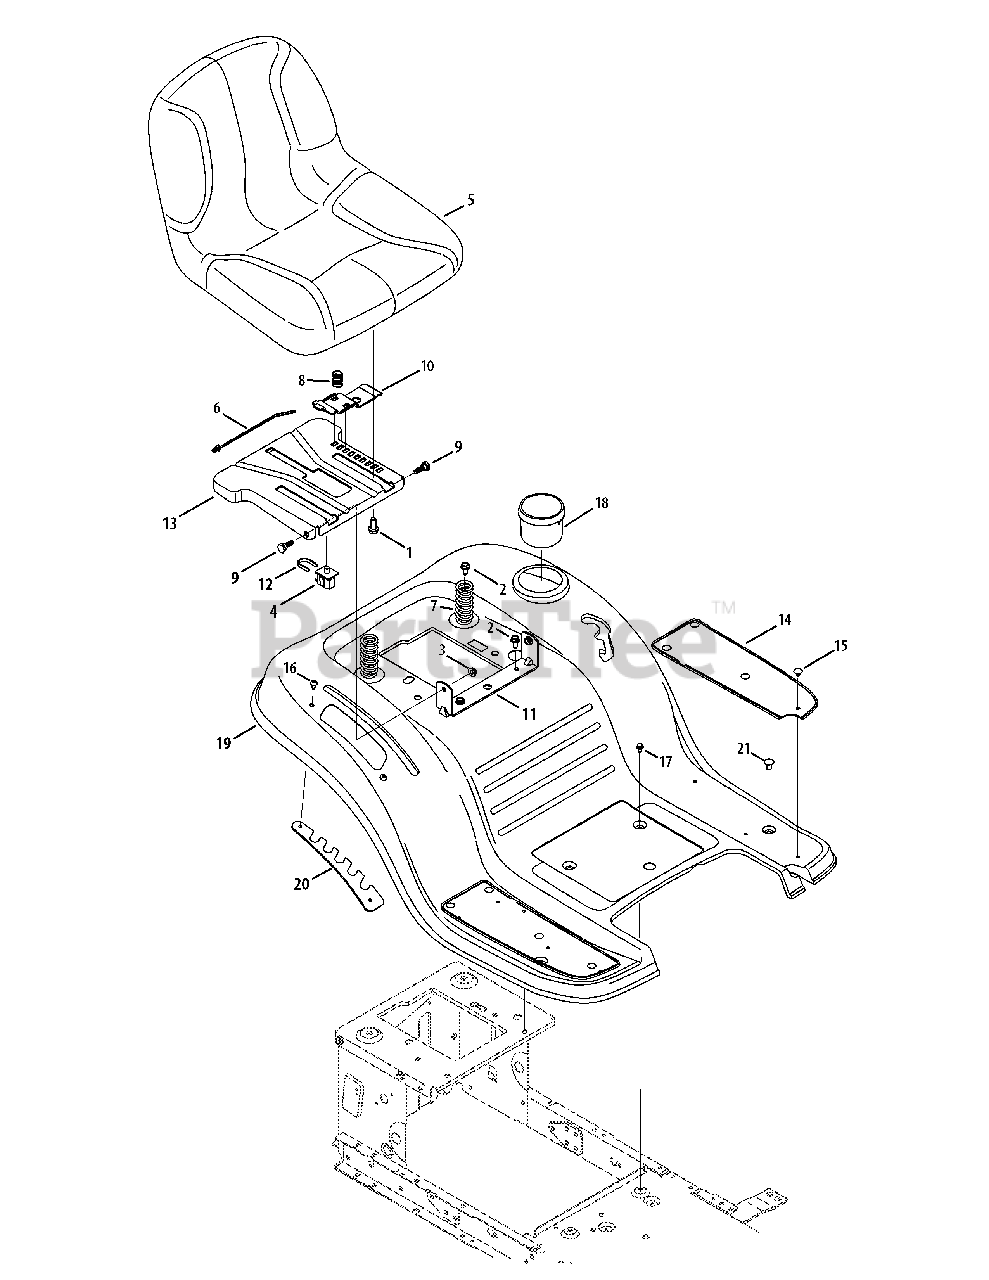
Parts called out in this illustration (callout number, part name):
1	Hex Flange Bolt, 3/8-16 x .875
2	Screw, Hd. Tapp, 5/16-18 x .75
3	Flange Lock Nut, 5/16-18
4	Seat Safety Switch
5	Seat
6	Push Mount Cable Tie
7	Spring, Compress., 1.28 x 3.125
8	Spring, Compress., .68 x 1.065 x .055
9	Shoulder Screw, 5/16-18 x .437 x .268
10	Seat Adjustment Lever
11	Seat Pivot Bracket
12	Switch Retainer Clip
13	Seat Mounting Bracket
14	Rubber Foot Pad, LH
14	Rubber Foot Pad, RH
15	Ratchet Clip, .250
16	Tap Screw, 1/4-20 x .5
17	Screw Pan Torx Head, 1/4-20 x .500
18	Cup Holder
19	Fender
20	Lift Adjuster Bracket
21	Carriage Screw, 1/4-20 x .62
